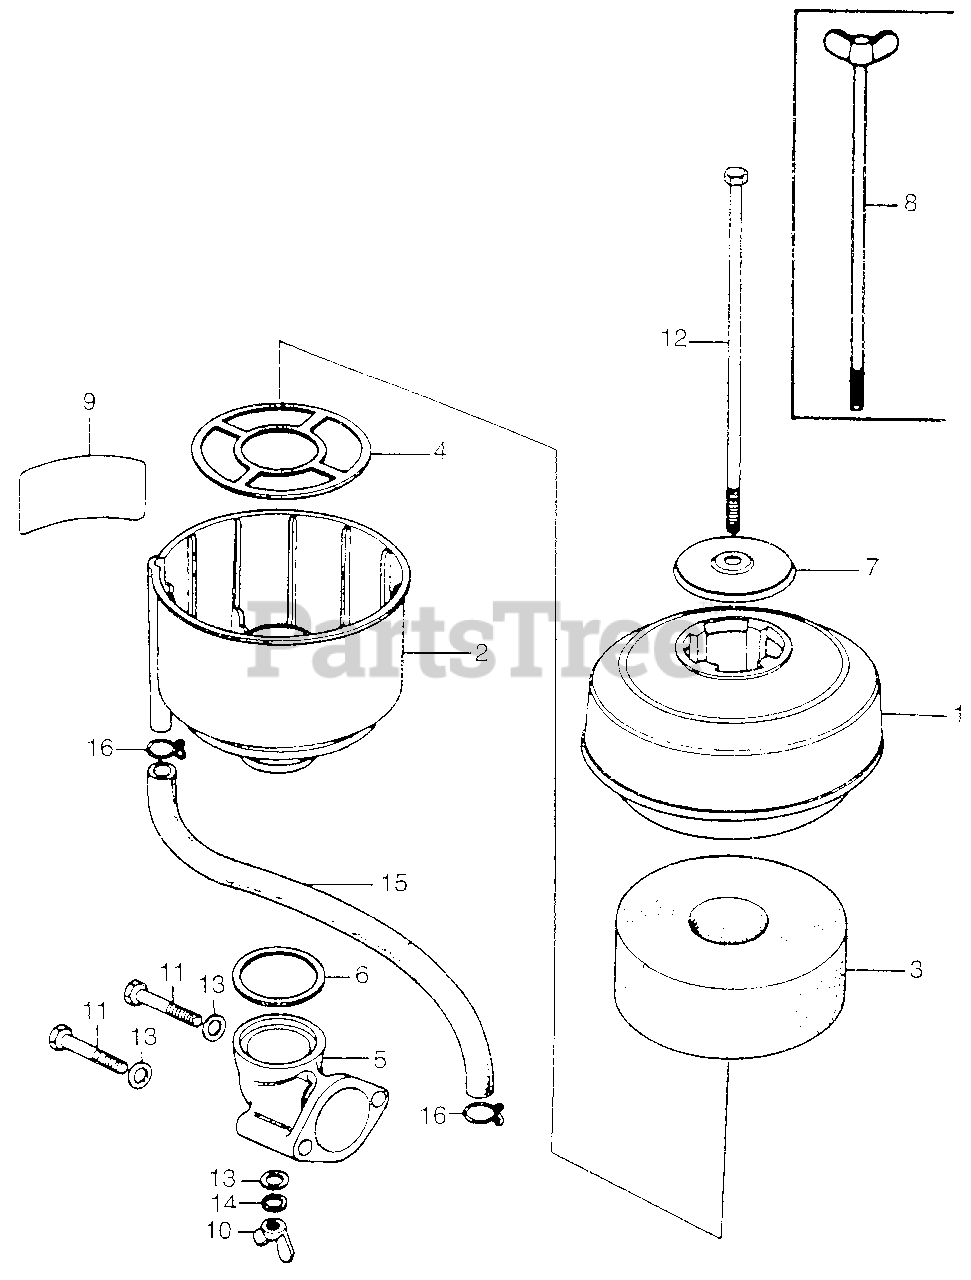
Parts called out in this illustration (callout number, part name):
1	BODY, CLEANER
2	PAN, AIR CLEANER OIL
3	ELEMENT, AIR CLEANER
4	GRID, AIR CLEANER
5	ELBOW, AIR CLEANER
6	GASKET, IN. ELBOW (NOT AVAILABLE)
7	CAP, AIR CLEANER
9	PLATE, OIL BATH CAUTION
10	WINGNUT (6MM) (NOT AVAILABLE)
11	BOLT, HEX. (6X40)
12	BOLT, HEX. (6X160)
13	WASHER, PLAIN (6MM)
14	WASHER, SPRING (6MM)
15	BULK HOSE, FUEL (8X1000) (8X200)
16	CLIP, TUBE (B8)
